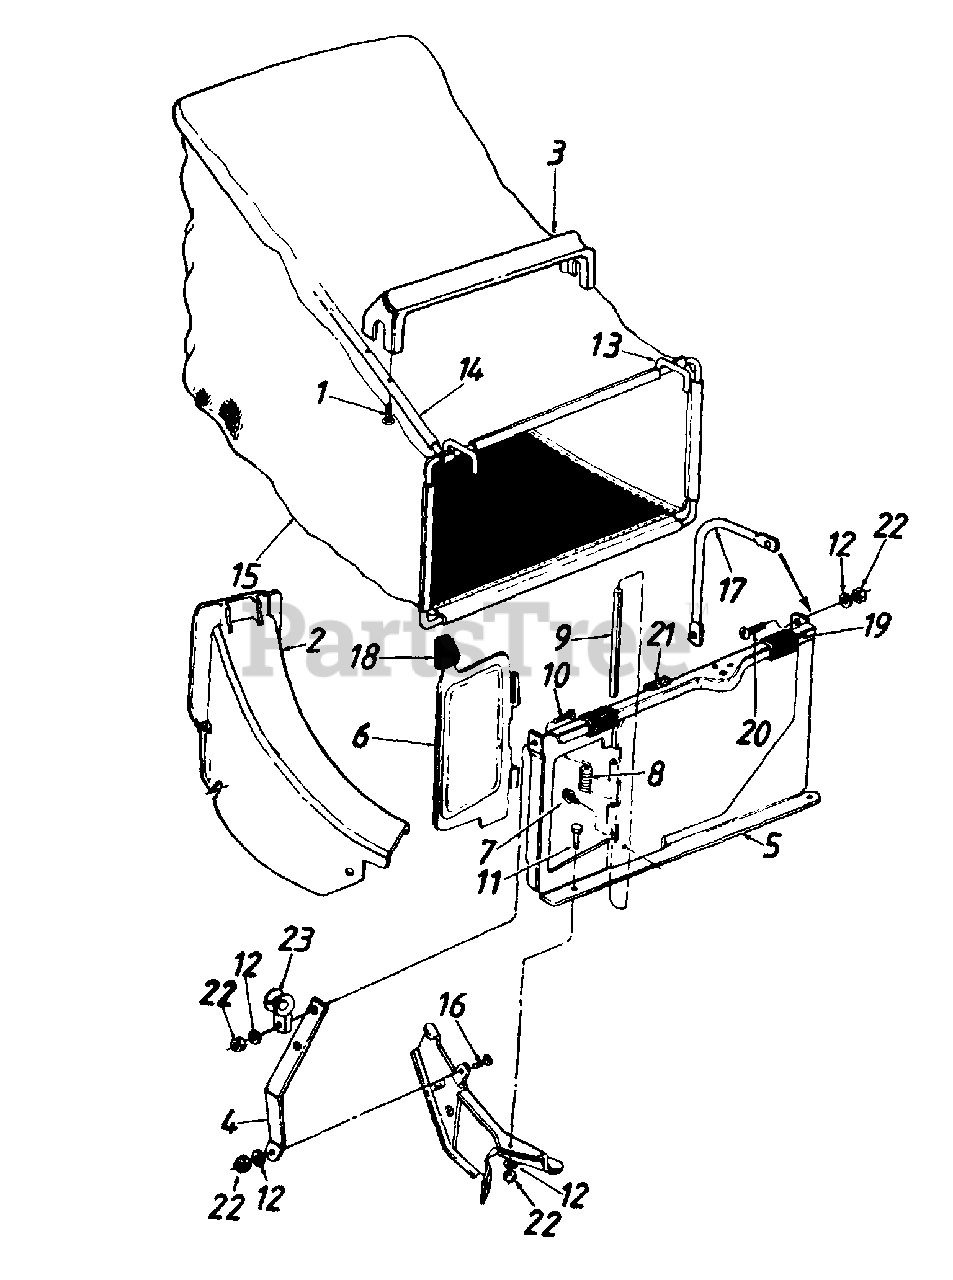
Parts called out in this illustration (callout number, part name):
1	Hex AB-Tap Scr. #12 x 1.25" Lg
2	Rear Discharge Chute Ass'y.
7	Hex B-Tap Scr. #10 x .38"
8	Torsion Spring
10	Truss Mach. Scr. 1/4-20 x 3/4" Lg.
11	Hex Bolt 1/4-20 x .50" Lg.
12	L-Wash. 1/4" I.D.
15	21" Rear Discharge Grass Bag
16	Hex Bolt 1/4-20 x .62" Lg.
17	Catcher Panel Support Arm
18	Door Grip
20	Truss Mach. Scr. 1/4-20 x .62" Lg.
22	Hex Nut 1/4-20 Thd.
